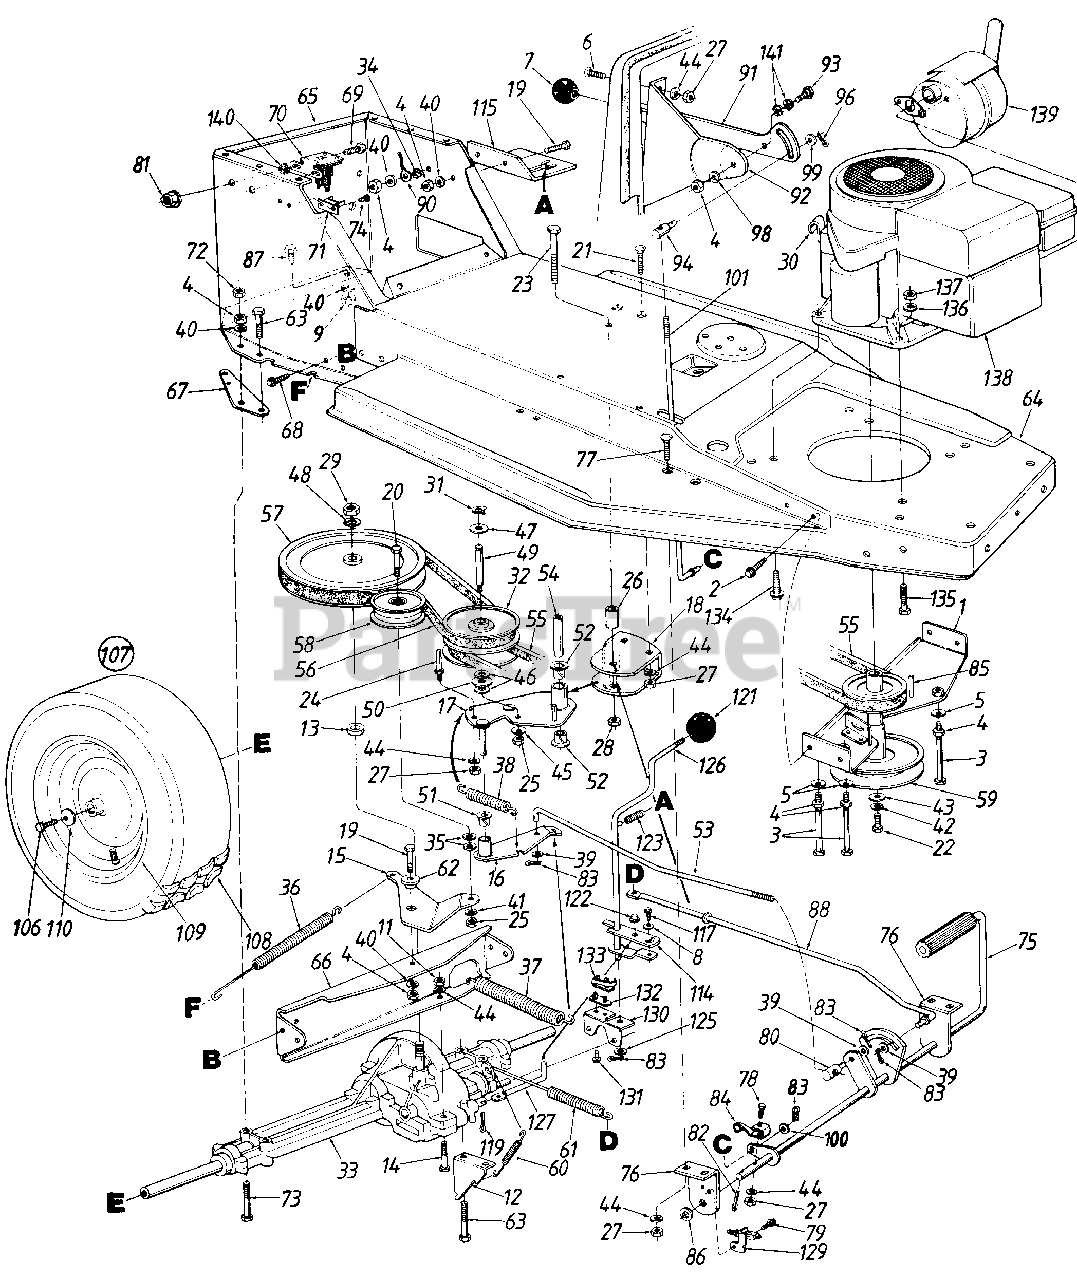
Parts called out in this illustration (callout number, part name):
1	Engine Pulley Belt Guard Ass'y.
2	Hex AB-Tap Scr. 1/4 x .62"
3	Hex Bolt 5/16-18 x 5-1/4" Lg.
4	Hex Nut 5/16-18 Thd.*
5	Bell-Wash. .345" I.D. x .88
6	Truss-Mach. Scr. 1/4-20 x .50" Lg.*
7	Shift Knob
8	Bell-Wash. .265" I.D. x .75
9	Hex Nut 5/16-24 Thd.-Gr. 5
11	Hex Nut 1/4-28 Thd.*
12	Spring Retainer Brkt.
13	Spacer.5" I.D.
14	Hex Bolt 1/4-28 x 1.75" Lg.
15	Idler Bracket
18	Variable Speed Pivot Brkt.
19	Hex Bolt 5/16-18 x .75" Lg.*
20	Hex Bolt 3/8-24 x 2.0" Lg. Gr. 5
21	Carr. Bolt 1/4-20 x .75" Lg.
22	Hex Bolt 7/16-20 x 1.5" Lg.
23	Hex Bolt 3/8-24 x 4.0" Lg.
24	Belt Guard Pin
25	Hex Nut 3/8-24 Thd.
26	Spacer.38" I.D.
27	Hex Nut 1/4-20 Thd.*
28	Hex Patch Nut 3/8-24 Thd.
29	Hex Jam Nut 1/2-20 Thd.
31	Snap Ring
32	Variable Speed Pulley Ass'y.
33	Transaxle Complete
34	Ext. L-Wash. 5/16" I.D.
35	Fl-Wash. 3/8" I.D. x 1.0" O.D.
36	Extension Spring 6.12" Lg.
37	Extension Spring 7.5" Lg.
38	Extension Spring 2.59" Lg.
39	Fl-Wash. .385" I.D. x .620"
40	L-Wash. 5/16" I.D.
41	L-Wash. 3/8" I.D.
42	L-Wash. 7/16" I.D.*
43	Fl-Wash. .450" I.D. x 1.25"
44	L-Wash. 1/4" I.D.*
45	Bell-Wash. .39" I.D. x 1.13"
46	Fl-Wash. .56" I.D. x 1.0" O.D.
47	Washer "Teflon" .565 I.D.
48	Bell-Wash. 1/2" I.D. x 1.0" O.D.
49	Shaft .56" Dia. x 3.875" Lg.
50	Thrust Brg. 1.25 O.D.
51	Flanged Nyliner Brg.
52	Nyliner Flanged Brg.
53	Speed Control Link
55	V-Belt
56	V-Belt
57	1/2 V-Pulley .500" I.D. x 8.00"
58	Idler Pulley 3-1/8" Dia.
59	Dbl. Pulley 6.0" Dia. x 3.56"
60	Extension Spring 3.18" Lg.
61	Extension Spring 7.08" Lg.
62	Shld. Spacer .500" Dia.
63	Hex Bolt 5/16-18 x 2.75" Lg.
64	Front Frame
65	Rear Frame
66	Transaxle Support Brkt.
69	Hex Bolt 1/4-20 x .62" Lg.
70	Solenoid
71	Circuit Breaker
72	Hex L-Nut 5/16-18 Thd.
73	Hex Bolt 5/16-18 x 3.0" Lg.
74	Truss Mach. B-Tap Scr. #10 x.50" Lg.
75	Clutch/Brake Pedal Ass'y.
76	Clutch/Brake Pedal Mounting Brkt.
77	Carr. Bolt 1/4-20 x .62" Lg.
78	Hex Bolt 1/4-20 x 1.0" Lg.*
79	Hex TT-Tap Scr. 1/4-20 x .51"
80	Ferrule
81	Hex Sems Nut 1/4-20 Thd.
82	Cot-Pin 3/32" Dia. x 1.0" Lg.
83	Cot-Pin 3/32" Dia. x .75" Lg.
84	Switch Actuator
85	Sq. Key 1/4 x 2.0" Lg.
86	Fl-Wash. .635" I.D. x 1.0"
87	Hex Bolt 5/16-24 x .75" Lg.
90	Ground Wire 7.25" Lg.
91	Speed Selector Lever
92	7 Speed Selector Brkt.
93	Shld. Bolt .437" Dia. x .35" Lg.
94	Ferrule
96	Intern. Cot-Pin 5/16" Dia.
98	L-Wash. 5/16 I.D.*
99	Fl-Wash. .344" I.D. x .62"
100	Fl-Wash. .25" I.D. x .62" O.D.
101	Speed Control Rod
106	Hex L-Bolt 5/16-24 x .75" Lg.
107	Rear Wheel Ass'y. Comp.
110	Bell-Wash. .345" I.D. x .88"
114	Shift Lever Adjusting Link
115	Shift Lever Spring Brkt.
117	Hex Bolt 1/4-20 x .50 Lg.
119	Intern. Cotter Pin
121	Ball Knob
122	Retaining Ring
123	Compression Spring 1.5" Lg.
125	Fl-Wash. .469" I.D. x .88"
129	Safety Switch
130	Shift Lever Support
131	Hex Wash. Hd. #8 x .50" Lg.
132	Insulator Nut Plate
133	Spring Switch
134	Hex Wash. Hd. Tap Scr.-3/8-16 x 1.25" Lg.
135	Hex Bolt 5/16-24 x 1-1/4" Lg. Grade 5
136	L-Wash. 5/16" I.D.
137	Hex Nut 5/16-24 Thd.
138	Engine
139	Muffler
140	Ext. L-Wash. 1/4" I.D.
141	Wave Wash. .445" I.D.
